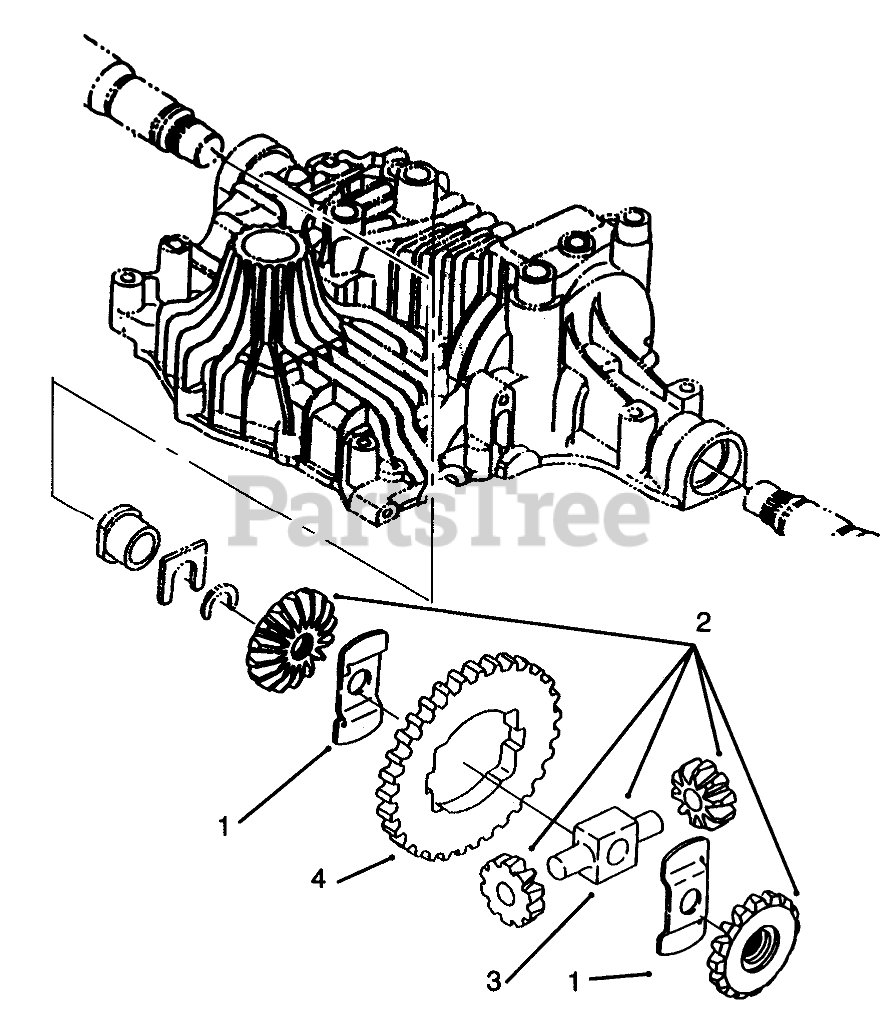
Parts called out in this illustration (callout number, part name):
1	Washer-Thrust (Only On: 72043, 72063, 72103)
2	Differential Gear ASM (Only On: 72043, 72063, 72103)
3	Shaft-Pinion (Only On: 72043, 72063, 72103)
4	Gear-Final (Only On: 72043, 72063, 72103)
